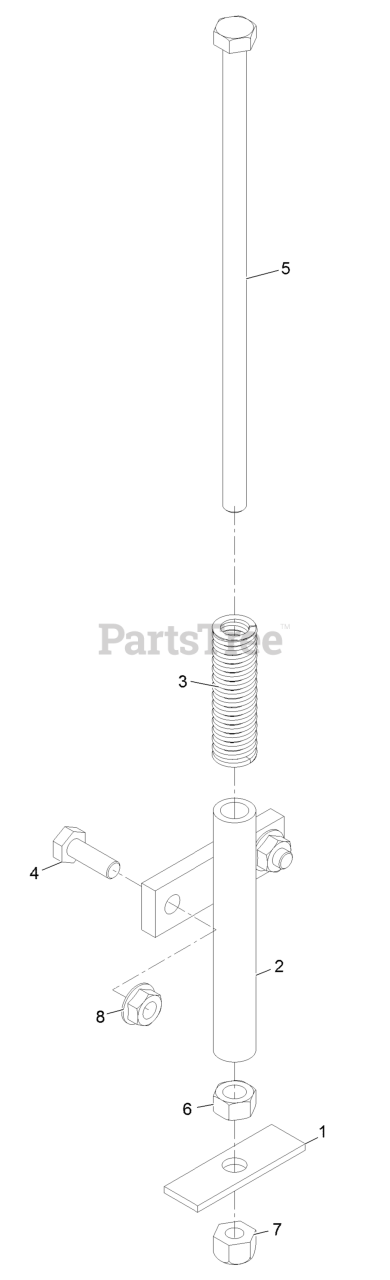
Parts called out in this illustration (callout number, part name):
1	PLATE-SWITCH, SEAT
2	MOUNT-SPRING, SEAT
3	SPRING-SWITCH, SEAT
4	SCREW-HH
5	SCREW-HH
6	NUT-HEX
7	NUT-LOCK, NI
